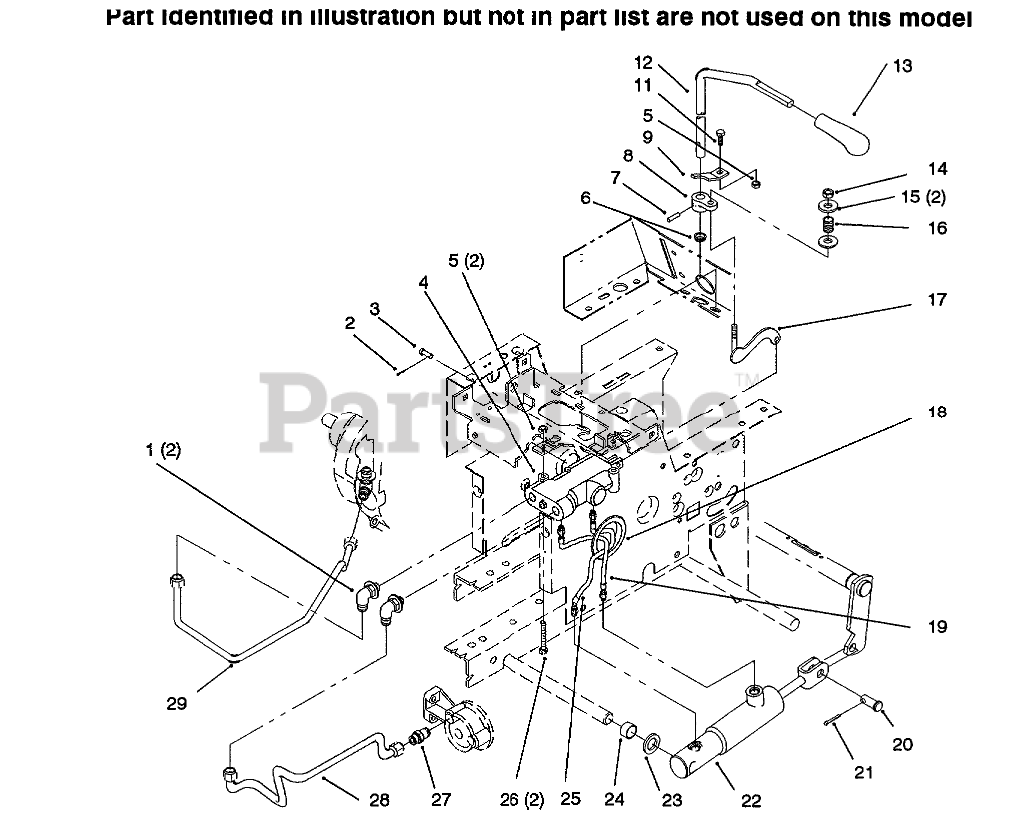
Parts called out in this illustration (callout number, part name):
1	ELBOW
2	PIN-COTTER
3	PIN-CLEVIS
4	ASS'Y-VALVE
5	NUT-LOCK, NI
6	NYLINER BUSHING
7	SPIROL PIN 7/32X7/8
8	ARM-CONTROL
9	BRACKET-CONTROL R B
11	SCREW-HH
12	ROD-LIFT CONTROL
13	Knob-Lift
14	NUT-LOCK, NI
15	WASHER-PLAIN
16	SPRING
17	WLDMT-LIFT BAR
18	GROMMET
19	Hose ASM-Hydraulic
20	Pin-Clevis
21	PIN-COTTER
22	ASS'Y-CYLINDER
23	Washer
24	SPACER-OUTER
25	Hose ASM-Hydraulic
26	SCREW-HH
27	FITTING
28	TUBE-HYD RETURN
29	TUBE-HYD PRESSURE
